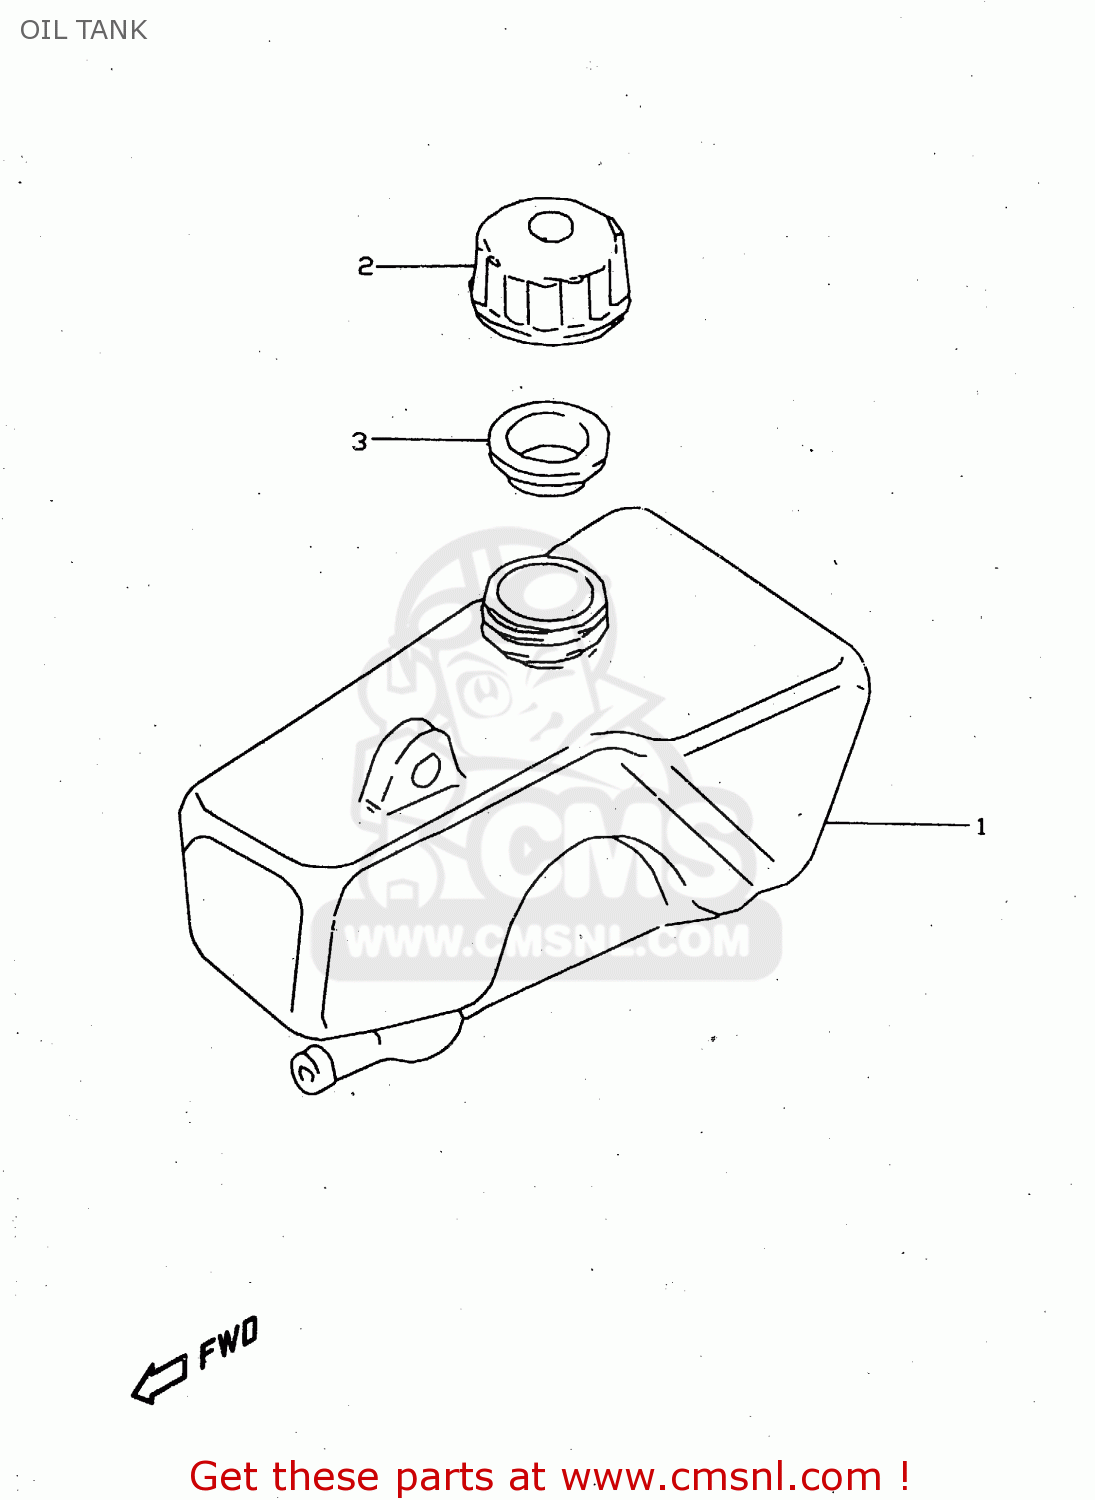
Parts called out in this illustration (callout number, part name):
1	TANK,OIL
2	CAP,OIL TANK FILLER
3	GASKET,OIL TANK (NAS)
